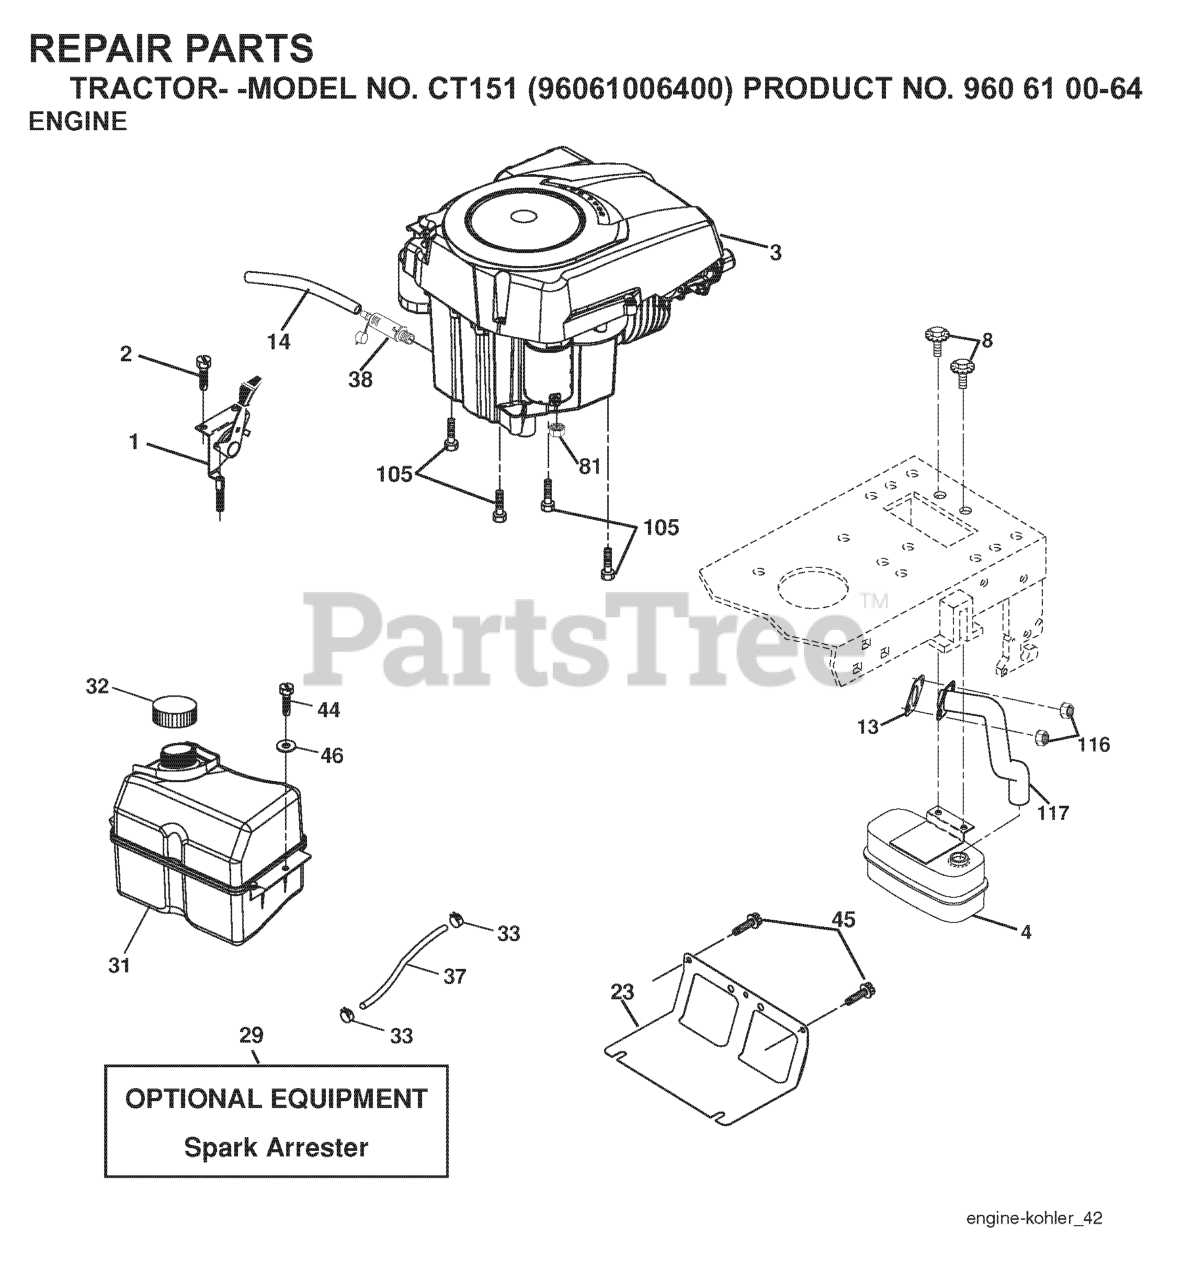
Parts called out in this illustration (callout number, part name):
1	CONTROL.THROTTLE.LT/YT
2	SCREW
4	MUFFLER.SINGLE.CYL.KOHL/B&S
8	BOLT.5/16-18UNCX3/4 W/SEMS.BLK
13	GASKET.EXHAUST.KOHLER
14	TUBE, DRAIN OIL ASM.
23	SHIELD.BROWNING.DBR.GUARD
29	KIT.SPARK ARRESTOR 794945 B&S
31	TANK FUEL
32	FUEL CAP
33	HOSE CLAMP
37	LINE.FUEL.20
38	PLUG DRAIN OIL EASY
44	SCREW HEXWSHR 1/4-20X3/4
45	SCREW, 3/8-16X3/4
81	NUT
105	SCREW 3/8-16X1
116	NUT.HEX.FLANGE.TOPLOCK
117	RP.TUBE.EXHAUST.KOHL.COURAGE
